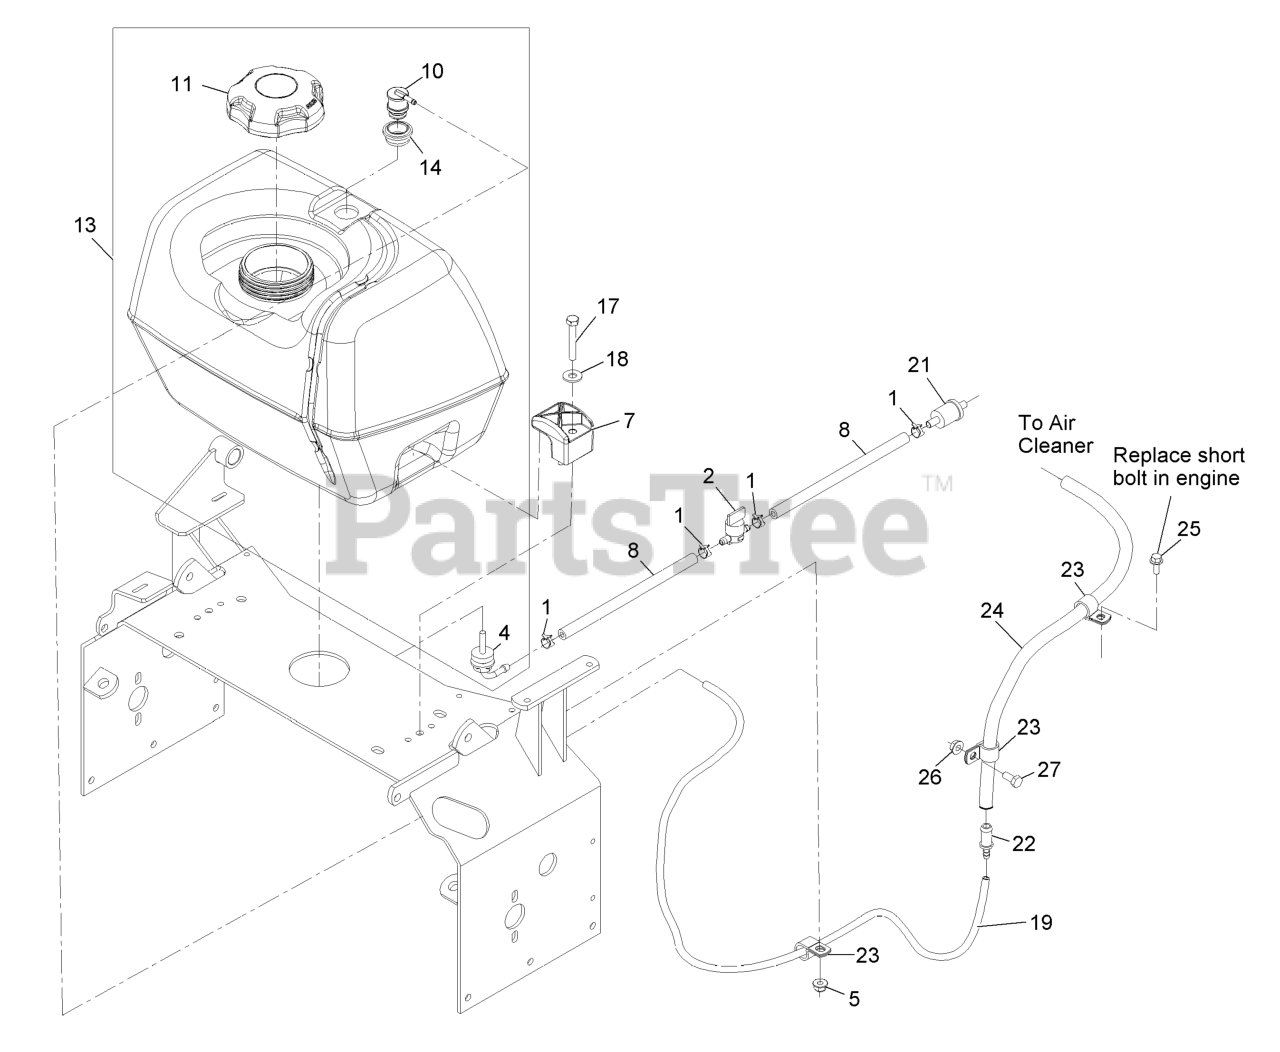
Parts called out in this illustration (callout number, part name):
1	CLAMP-HOSE
2	VALVE-FUEL
4	FITTING-FUEL, BULKHEAD
5	NUT-HF, NI
8	HOSE-FUEL
10	VALVE-VENT, FUEL
13	ASM, FUEL TANK
14	GROMMET
17	SCREW-HH
18	WASHER-FLAT
19	HOSE, EMISSIONS
21	Pn 24 050 13 Filter-Fuel
22	FITTING-STRAIGHT
23	CLIP-LOOM
24	HOSE-FUEL
25	SCREW-HHF
27	SCREW-HH
